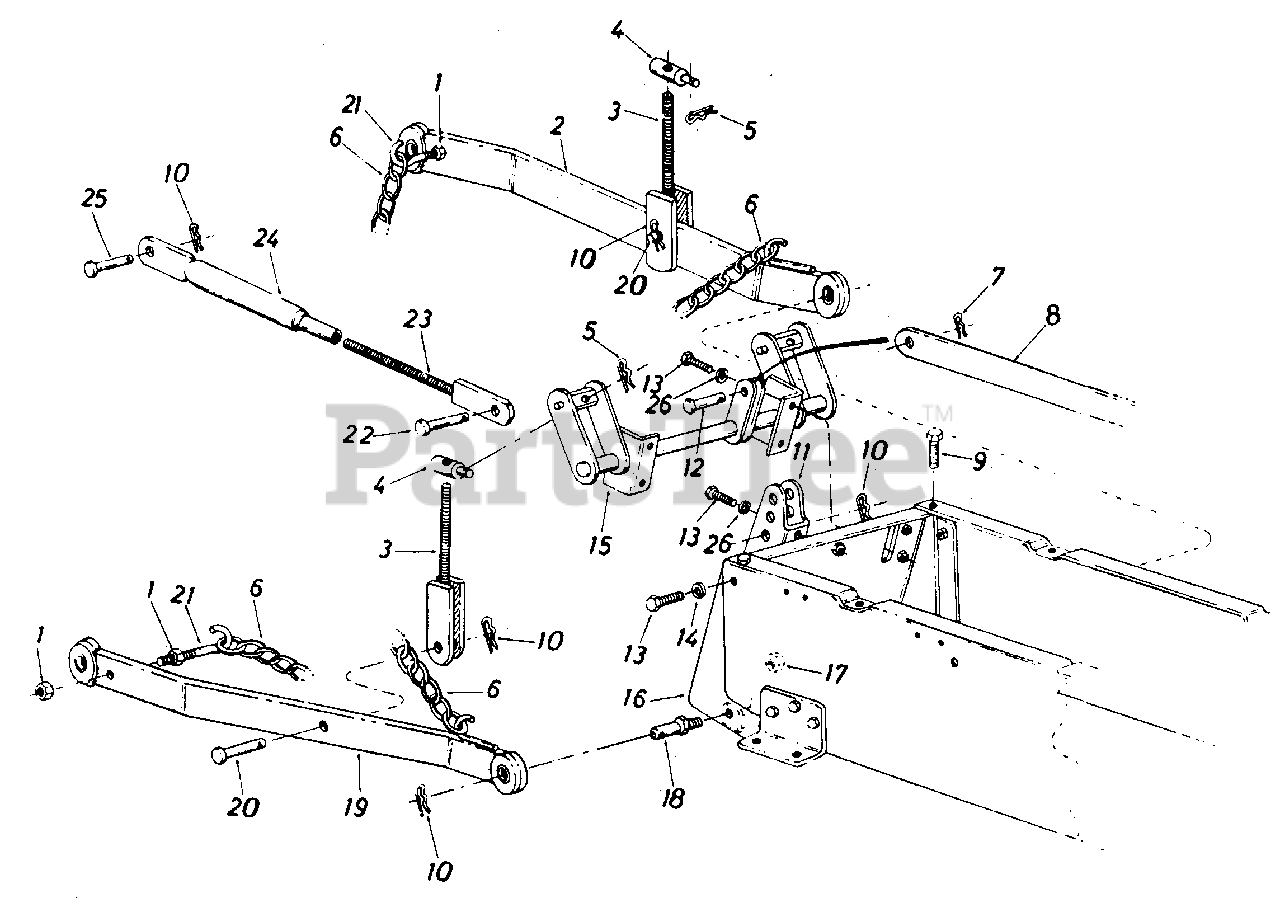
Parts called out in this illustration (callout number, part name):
1	Hex Cent. L-Nut 7/16-14 Thd.
2	Draft Bar Ass'y. L.H.
3	Clevis Screw Ass'y.
4	Clevis Pin
5	Hitch Pin Clip
6	Chain 20 Links
7	Cotter Pin 1/8" Dia. x 1.25" Lg.*
8	Push Bar Ass'y.
9	Hex Scr. 3/8-16 x .75" Lg.*
10	Hairpin Cotter
11	Hitch Brkt.
12	Clevis Pin
13	Hex Scr. 3/8-16 x .75" Lg.*
14	L-Wash. 3/8" Scr. H.D.*
15	Rear Lift Shaft Ass'y.
16	Hitch Plate Ass'y.
17	Hex Cent. L-Nut 5/8-18 Thd.
18	Link Clevis Pin
19	Draft Bar Ass'y. R.H.
20	Clevis Pin .63 Dia. x 1.66" Lg.
21	Hitch Chain Hook
22	Clevis Pin .63 Dia. x 2.4" Lg.
23	Clevis Screw
24	Clevis Tubing
25	Clevis Pin .63 Dia. x 2.4" Lg.
26	L-Wash. 3/8" Scr. H.D.
